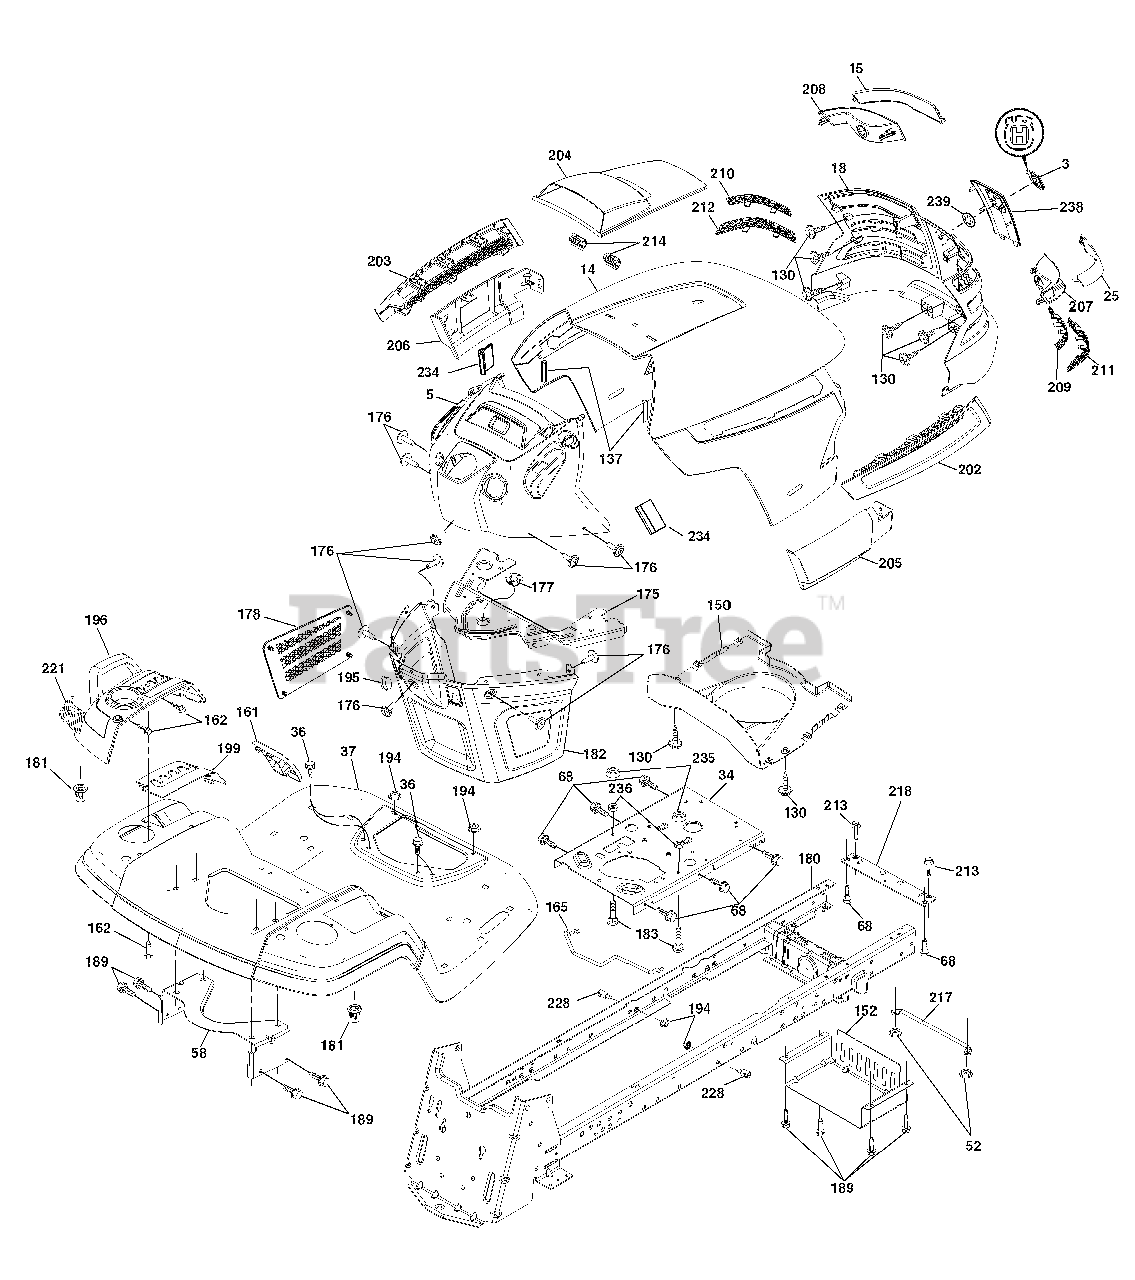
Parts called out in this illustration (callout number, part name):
3	Logo Husq.
14	Hood
34	Plate Engine
36	Screw 5/16-18 x 3/4
37	Fender
52	Nut Crown Lock 5/16-18
58	Bracket Fender
68	Screw 5/16-18 x 1/2
130	Screw #10 x 0.750 BOS Thread
137	Bumper Dash
150	Duct Heat Hood
152	Shield Browning/Debris
161	Console Fuel Window
162	Screw Hex Wsh Hi-Lo 1/4 x 1/2
165	Bracket Support Tank
175	Crossmember
176	Screw 10-24 x 5/8 Wshd Qdrx
177	Bushing Steering
178	Cargo Asm. Net
180	Chassis
181	Bushing Mtg. Fender Crgo.
182	Dash Lower
183	Bolt Fin Hex 5/16-18 unc x 1-1/4
189	Screw 5/16-18 x 3/4
194	Nut Lock Hex Flange 5/16-18
195	Plug Cruise/Phone
196	Console Asm. Deck Lift
199	Plate Deck Lift
202	Vent Side Hood RH
203	Vent Side Hood LH
204	Vent Asm Hood Top
205	Skirt Hood Side RH
206	Skirt Hood Side LH
209	Insert Hex Top RH
210	Insert Hex Top LH
211	Insert Hex Bottom RH
212	Insert Hex Bottom LH
213	Bolt Hex HD 5/16-18 unc x 3/4
214	Clip Retainer
221	Reflector LH
228	Stud Fastener
234	Bumper Hood
235	Spacer Fender
236	Nut Center Lock 5/16-18 unc
238	Trim Husq.
